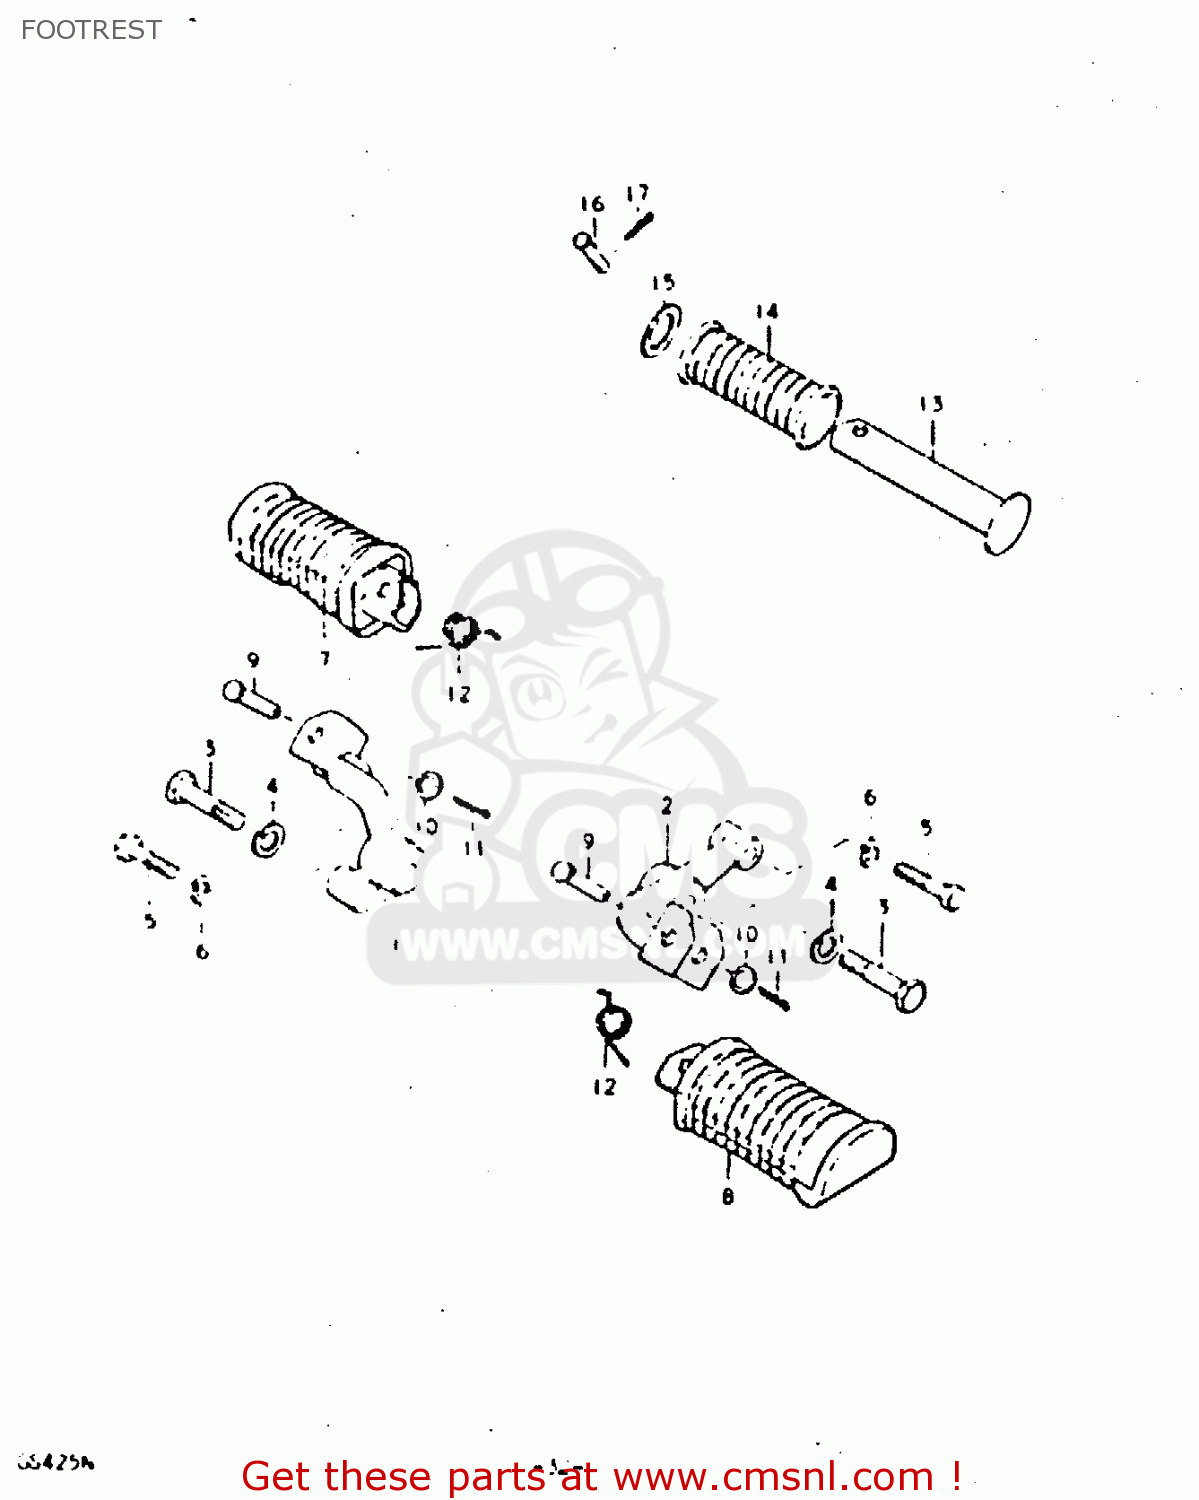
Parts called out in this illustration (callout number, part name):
1	BAR,FRONT FOOTREST
2	BAR,FRONT FOOTREST,LEFT
3	BOLT
4	LOCK WASHER
5	BOLT 8X40
6	LOCK WASHER
7	RUBBER,FRONT FOOTREST
8	FOOTREST
9	PIN
10	WASHER
11	PIN 20X20
12	SPRING
13	BAR,FOOTREST RUBBER
14	RUBBER,PILLION FOOTREST
15	WASHER (19.5X32X2)
16	PIN
17	PIN 20X20
